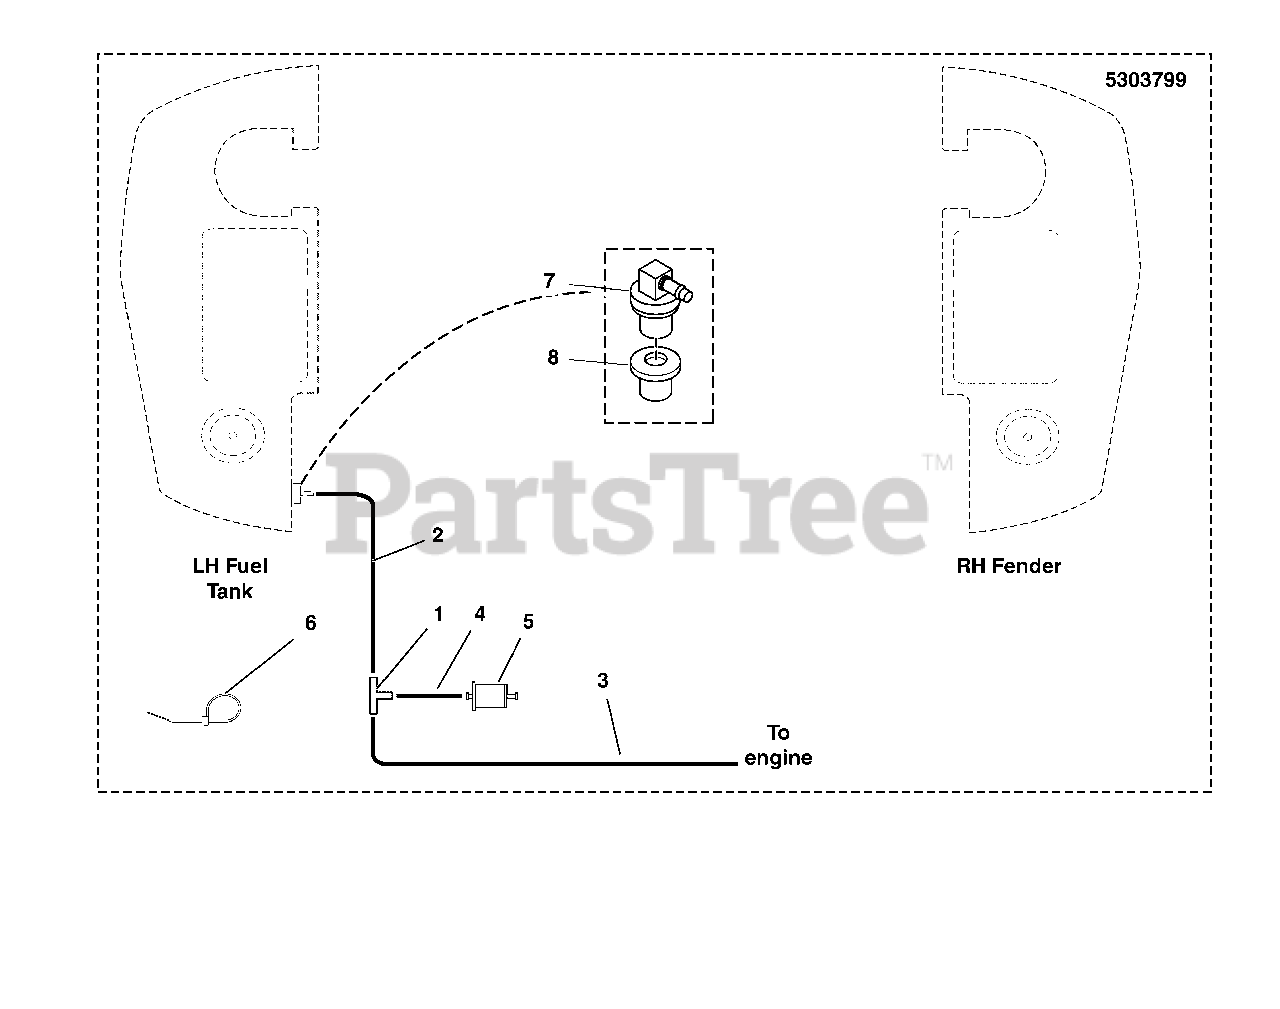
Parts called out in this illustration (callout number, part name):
1	FITTING, 3/16" TEE, BARB TYPE, HDPE
2	HOSE, VAPOR, 5MM ID, 30.00 LG
3	HOSE, VAPOR, 5MM ID, 12.00 LG
4	HOSE, VAPOR, 5MM ID, 2.00 LG
5	FILTER, Fuel
6	TIE,SELF-LOCKING, 6"
7	REMOTE VENT ASSEMBLY, NO VALVE (SV)
8	GROMMET (SV)
